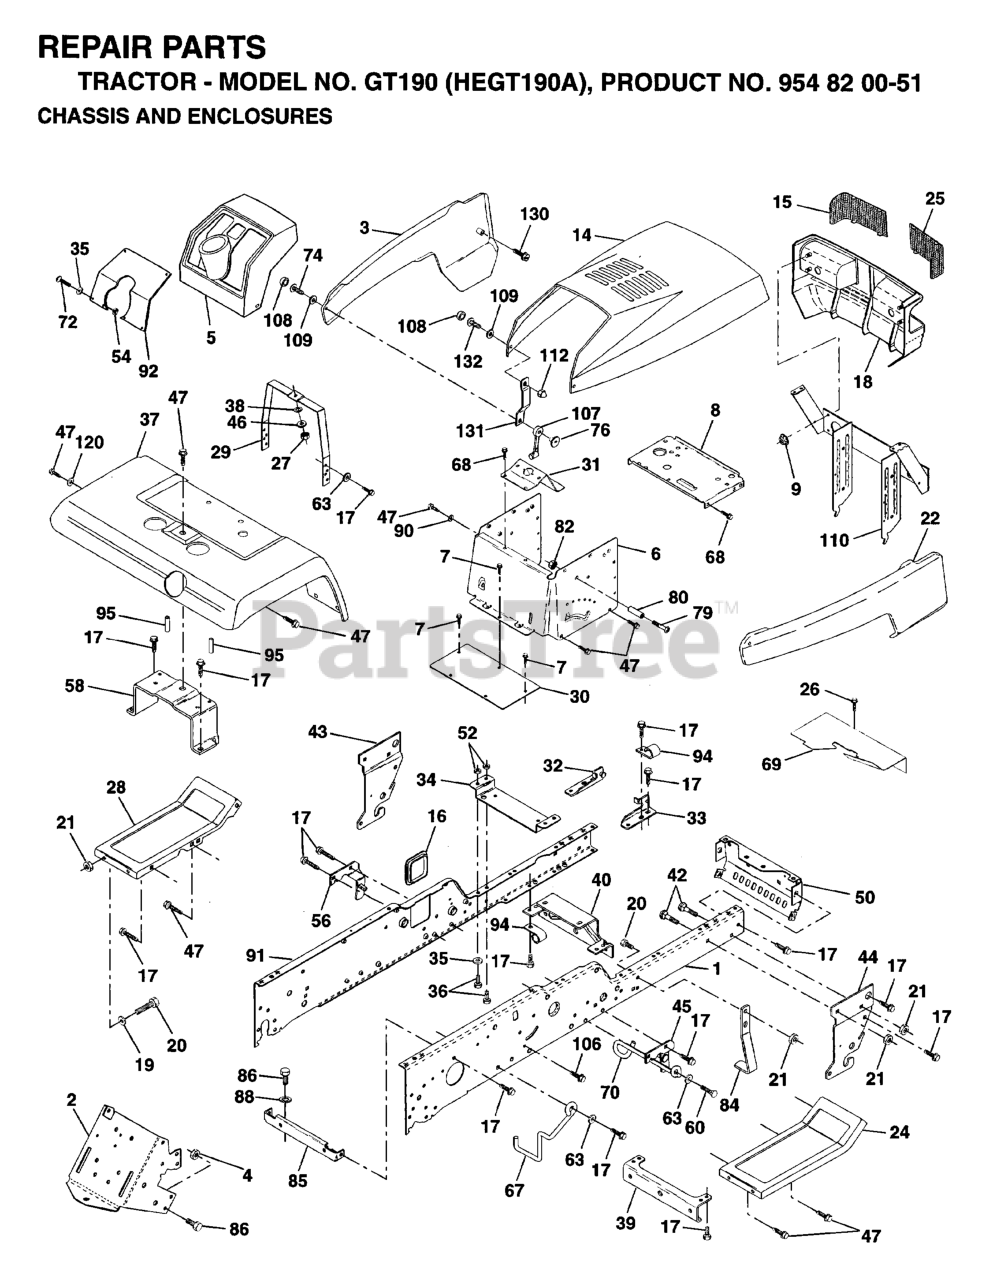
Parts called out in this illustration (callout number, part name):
1	RAIL, FRAME RH
2	DRAWBAR-GT
3	SIDE PANEL LH
4	Nut, Crownlock Hex 7/16-14 unc
6	DASH ASS'Y LOWER
7	SCREW
8	SUPPORT, BATTERY
9	PAL NUT LT
14	HOOD ASM PNT
15	LENS RH
16	COVER ACCESS
17	SCREW
18	GRILL COMPLETE
19	WASHER
20	BOLT
22	PANEL ASM SD RH
24	FOOTREST RH
25	LENS LH
26	SCREW.THDROL.5/16-18X3/4.TTY
27	NUT
28	FOOT REST LH
29	DASH SUPT YP
31	BRACE, SUPPORT STEERING
32	FRAME PIVOT BRKT ASSY LH
33	FRAME PIVOT BRKT ASSY RH
34	ENGINE SUPPORT BRKT
35	WASHER
36	BOLT.FIN.HEX.5/16-18X3/4
37	FENDER
38	LOCKWASHER
39	FRONT AXLE BRACKET
40	AXLE SUPPORT BRKT
42	BOLT D
43	FRONT SUSPENSION BRKT LH
44	FRONT SUSPENSION BRKT RH
45	CHASSIS BRKT
50	CHASSIS BRKT
52	LOCKNUT
54	NUT
56	SUSPENSION BRKT LH
58	FENDER BRKT
60	SCREW
63	WASHER
67	BELT GUIDE
68	Screw 5/16-18 x 1/2 Hex, Self Tapping 5/16-18 x 1/2
70	BELT GUIDE
72	Screw, Machine, Truss Head 5/16-18 UNC x 3/4
74	SCREW
76	WELDNUT
79	RP SCREW
82	NUT **
84	MOWER STOP
85	BRACKET SUPPORT PNT TRANS VGT
86	BOLT
88	LOCKWASHER
90	LOCKWASHER
91	RAIL, FRAME LH
95	NUT-PUSH YT
106	SCREW
107	LATCH.HOOD.
108	SNAP CAP LT
110	PIVOT ASM GRL/HD
112	NUT
120	WASHER
130	Screw, SLTD Hex Hd. W/Pl Washer
131	BRACKET.SUPPORT.HOOD/PANEL.NLA
